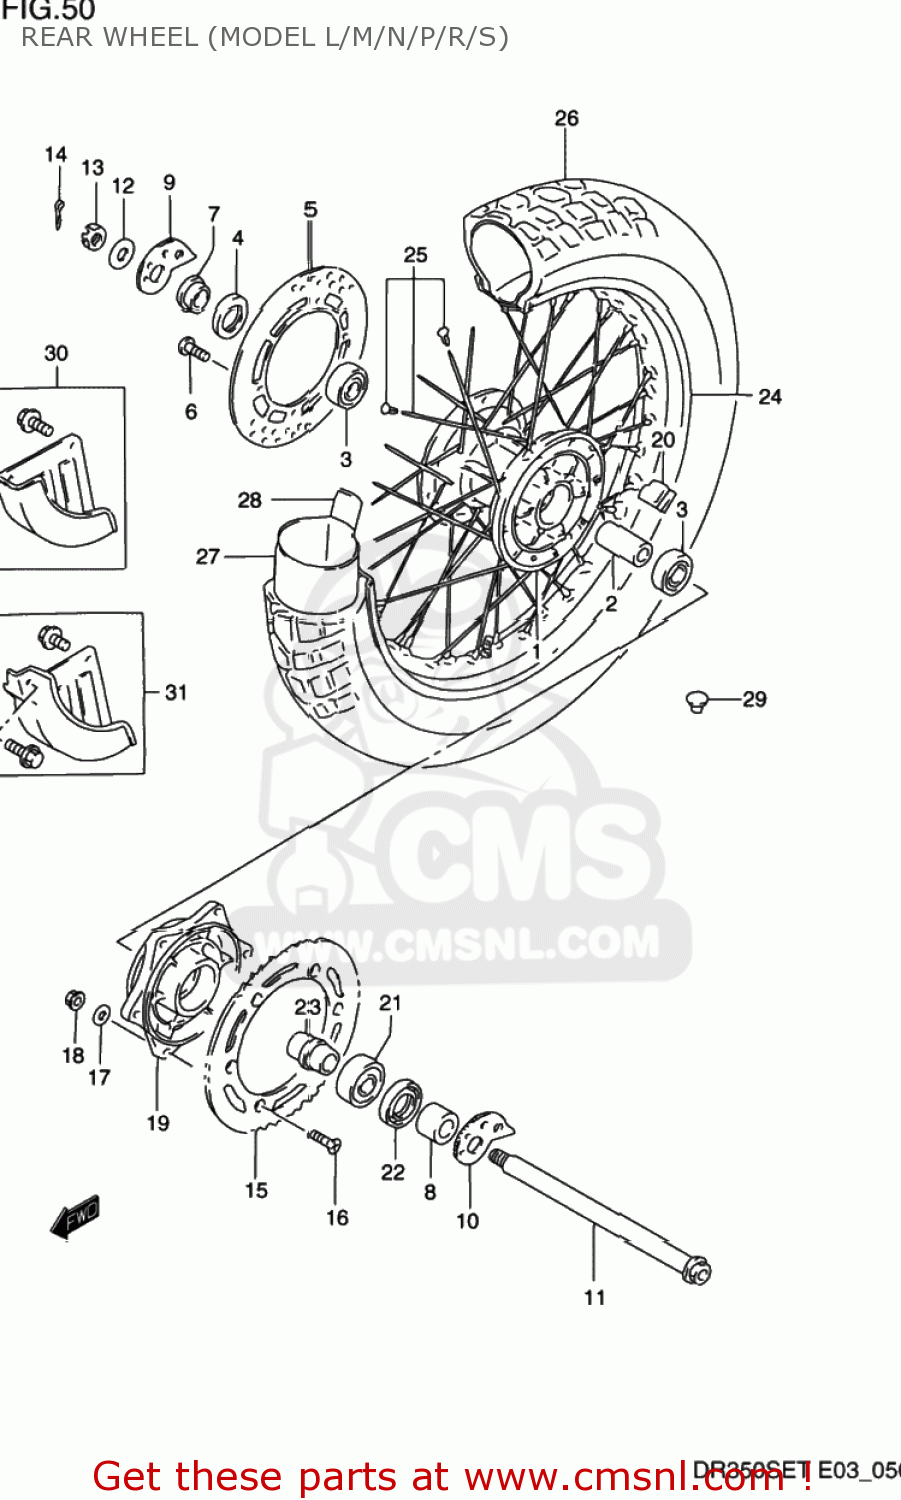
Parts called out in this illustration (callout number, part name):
1	HUB,RR WHEEL
2	SPACER,RR HUB BEARING
3	BEARING
4	SEAL,OIL(26X47X5)
5	DISC,RR BRAKE
6	BOLT
7	SPACER,RR AXLE,R
8	SPACER,RR AXLE,L
9	ADJUSTER,CHAIN
10	ADJUSTER,CHAIN,L
11	AXLE,RR
12	WASHER(19X32X3.2)
13	NUT
14	PIN,COTTER
15	SPROCKET,REAR
16	BOLT(8X30.5)
17	WASHER
18	NUT
19	DRUM,REAR SPROCKET MOUNT
20	ABSORBER,RR HUB SHOCK
21	BEARING(25X52X15)
22	SEAL,OIL(34X52X6)
23	RETAINER,RR SPROCKET DRUM
24	RIM,REAR WHEEL (18X2.15)
25	SPOKE SET,RR WHEEL
26	TIRE
27	TUBE ASSEMBLY,WHEEL,INNER
28	PROTECTOR,WHL INR TUBE
29	CAP(OD:12)
30	COVER SET,REAR BRAKE DRUM
31	COVER SET,RR BRAKE DISC
